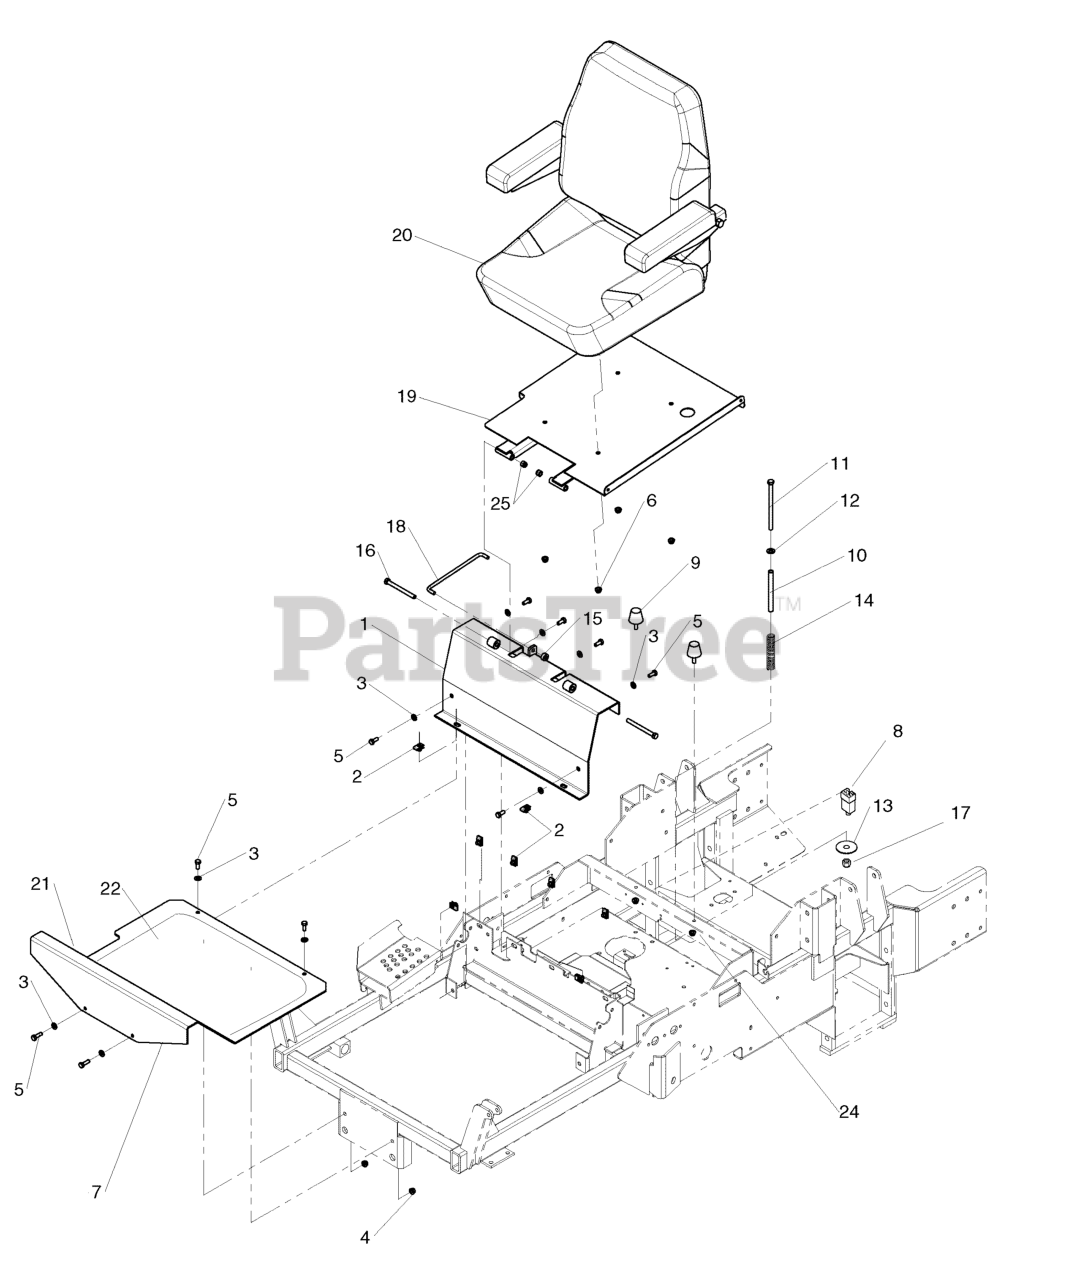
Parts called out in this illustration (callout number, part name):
1	SEAT PLATE W/ DECALS, IS5100Z
2	BODY CLIP, 5/16-18-7GA MATERIAL
3	WASHER, 5/16" SAE
4	NUT, 5/16-18 HEX SERRATED FLANGE (LARGE)
5	BOLT, 5/16-18 X 1" GD5
6	NUT, 5/16-18 HEX NYLOCK FLANGE
7	PLATE, FLOOR DETAIL - RED
8	SWITCH, PLUNGER, N.C./N.C.
9	BUMPER, RUBBER 5/16-18
10	SPACER, .38 X .50 X 5.06
11	BOLT, 3/8-16 X 6" GD5 CZ
12	WASHER, 3/8 SAE
13	WASHER, 2.00 X .390 X .135
14	SPRING, COMP, .835 X.105 X4.26
15	COLLAR, 5/16" SET
16	BOLT, 3/8-16 X 4" GD5 CZ
17	NUT, 3/8-16 HEX NYLON LOCK
18	ROD, SEAT STOP
19	WELD, SEAT MOUNT - RED
21	SAFETY WALK, 17.38 X 6.00
22	SAFETY WALK, 11.50 X 17.38
23	NUT, 5/16-18 HEX SERRATED FLANGE (SMALL)
24	NUT, 3/8-16 HEX NYLON FLANGE
